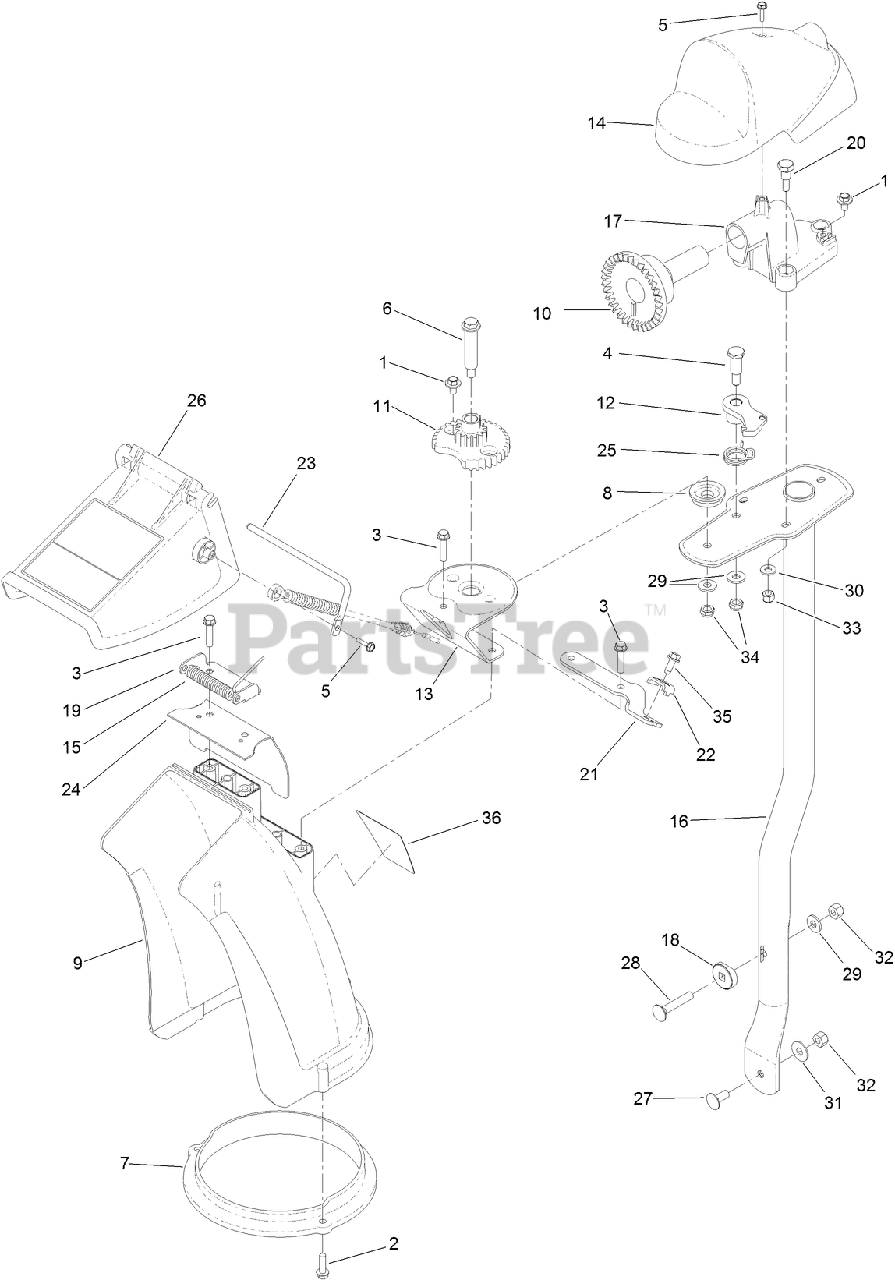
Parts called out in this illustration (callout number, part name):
1	SCREW AND WASHER ASM
2	SCREW-HWH
3	SCREW-PLASTITE
4	SCREW-SHOULDER
5	SCREW-HWH
6	BOLT-SHOULDER
7	RING-CHUTE
8	SPACER-CHUTE
9	CHUTE-DISCHARGE
10	GEAR-FACE
11	GEAR-CHUTE
12	LATCH-CHUTE
13	BRACKET-SUPPORT, CHUTE
14	COVER-GEAR, CHUTE
15	SPRING-TORSION
16	TUBE-SUPPORT
17	MOUNT-GEAR, FACE
18	WASHER-CURVED
19	BRACKET-DEFLECTOR
20	SCREW-SHOULDER
21	BRACKET-CLAMP, CABLE
22	CLAMP-CABLE
23	ROD-DEFLECTOR
24	SEAL-CHUTE
25	SPRING-TORSION
26	DEFLECTOR-CHUTE, CE
27	SCREW-CARR
28	BOLT-CAR
29	WASHER-FLAT
30	WASHER-FLAT
31	WASHER-BELLEVILLE
32	NUT-LOCK, NI
33	NUT-LOCK, NI
34	NUT-LOCK, NI
35	SCREW-HWH
36	DECAL-GUARANTEE
